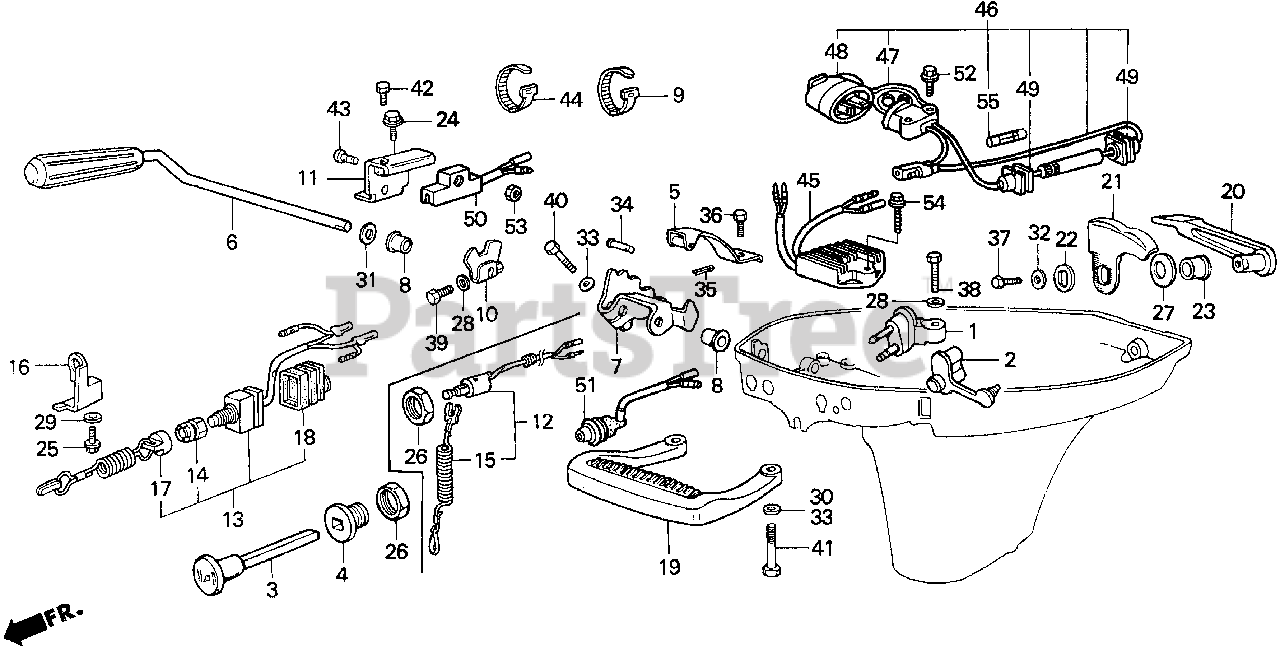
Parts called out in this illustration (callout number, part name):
1	CONNECTOR, FUEL *NH282MU* (OYSTER SILVER METALLIC-U)
2	CAP, FUEL JOINT
3	KNOB, CHOKE
4	GUIDE, CHOKE KNOB
5	SPRING, CLICK
6	SHAFT, SHIFT
7	ARM, GEARSHIFT
8	BUSH, SHAFT
9	TIE, CABLE
10	PLATE, SWITCH SHIELD
11	PLATE, SWITCH SETTING
12	SWITCH ASSY., EMERGENCY STOP
15	WIRE, EMERGENCY
19	HANDLE, CARRYING *NH282MU* (OYSTER SILVER METALLIC-U)
20	LEVER, COVER LOCK *NH282MU* (OYSTER SILVER METALLIC-U)
21	HOOK, COVER LOCK
22	WASHER, COVER LOCK
23	BUSH, COVER LOCK
24	BOLT, FLANGE (6X12)
26	NUT, HEX. (16MM)
27	SPRING, LEVER
28	WASHER, PLAIN (6MM)
30	WASHER, PLAIN (8MM)
31	WASHER, PLAIN (10MM)
32	WASHER (6MM)
33	WASHER, PLAIN (8MM)
34	PIN (5X17)
35	PIN, COTTER (1.6MM)
36	BOLT, HEX. (6X12)
37	BOLT, HEX. (6X16)
38	BOLT, HEX. (6X20)
39	BOLT, HEX. (6X28)
40	BOLT, HEX. (8X28)
41	BOLT, HEX. (8X32)
42	BOLT, HEX. (6X8)
43	SCREW, PAN (5X20)
45	RECTIFIER ASSY., REGULATOR
46	RECEPTACLE ASSY., CHARGE
47	RECEPTACLE
48	PLUG, RECEPTACLE
49	GROMMET, FUSE HOLDER
50	SWITCH ASSY., NEUTRAL
51	LAMP ASSY., INDICATOR
52	BOLT, FLANGE (5X22)
53	NUT, HEX. (5MM)
54	BOLT, FLANGE (6X25)
55	FUSE A (5A)
